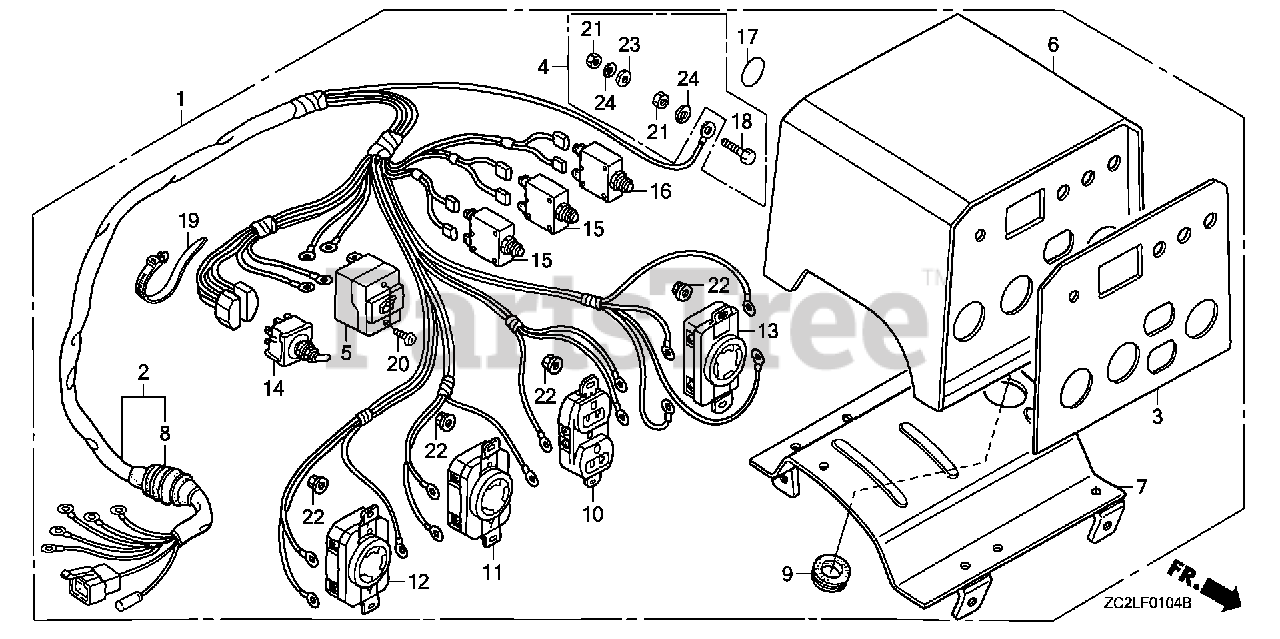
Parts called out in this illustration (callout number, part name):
1	BOX ASSY., CONTROL *R280* (POWER RED)
2	WIRE HARNESS ASSY.
3	MARK, PANEL SWITCH
4	TERMINAL SET, GROUND
5	BREAKER, CIRCUIT (19A)
6	BOX, CONTROL *R280* (POWER RED)
7	PLATE (LOWER) *R280* (POWER RED)
8	GROMMET, A.C. WIRE
9	GROMMET, MAIN WIRE
10	RECEPTACLE (20A/125V)
11	RECEPTACLE (20A/125V) (NOT AVAILABLE)
12	RECEPTACLE (30A/125V)
13	RECEPTACLE (30A/125-250V)
14	SWITCH ASSY., VOLT CHANGE
15	PROTECTOR, CIRCUIT (20A)
16	PROTECTOR, CIRCUIT (30A)
17	MARK, GROUND
18	BOLT, HEX. (6X28)
19	TIE, CABLE (NATURAL 225X5.0)
20	SCREW, PAN (4X6)
21	NUT, HEX. (6MM)
22	NUT, FLANGE (4MM)
23	WASHER, PLAIN (6MM)
24	WASHER, SPRING (6MM)
